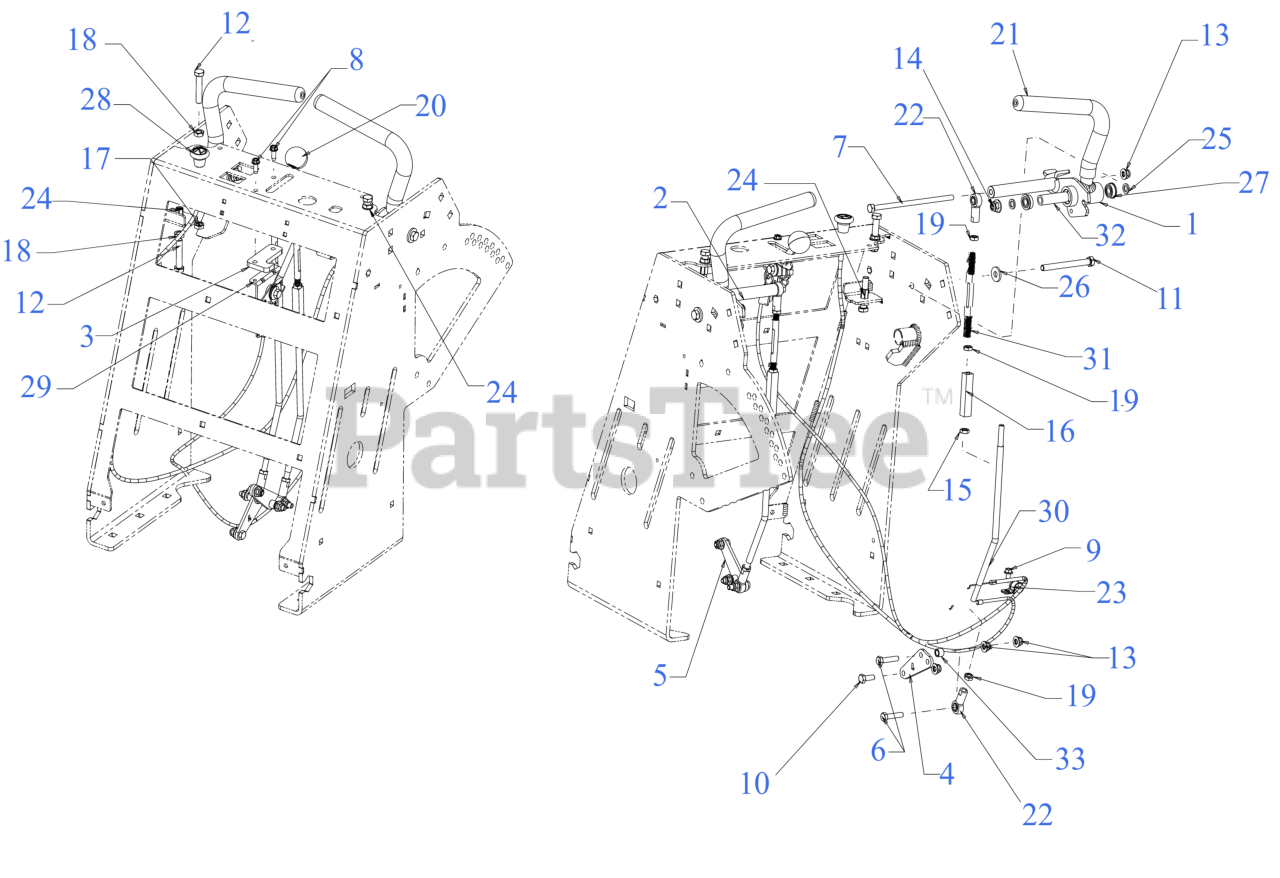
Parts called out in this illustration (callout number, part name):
1	CONTROL HANDLE (LH)
2	CONTROL HANDLE (RH)
3	THROTTLE STOP SPACER
4	PUMP ARM PLATE (LH)
5	PUMP ARM PLATE (RH)
6	SCREW 5/16-18 x 1.25 GR5
7	SCREW 5/16-18 x 6.00 GR5
8	SCREW 1/4-20 x .750
9	SCREW 1/4-20X.625
10	SCREW 5/16-18 x .75 GR5
11	SCREW 3/8-16 x 3.50 GR5
12	SCREW 3/8-16 x 2 GR5
13	FLANGE LOCK NUT 5/16-18
15	HEX JAM NUT 5/16-24 GR5
16	TURNBUCKLE 5/16-24 x 2.75
17	HEX JAM NUT 3/8X24
19	HEX JAM NUT 5/16-24 GR 5
21	GRIP .75ID x 1.0OD
22	ROD END 5/16 ID
24	RIV NUT 3/8-16
25	FLAT WASHER
27	FLANGE BEARING
28	CHOKE CABLE
29	THROTTLE CABLE
30	CONTROL ROD (LOWER)
31	CONTROL ROD (UPPER)
32	SPACER .379 x .63 x 1.957
33	SPACER 0.329 x 0.505 x 0.380
